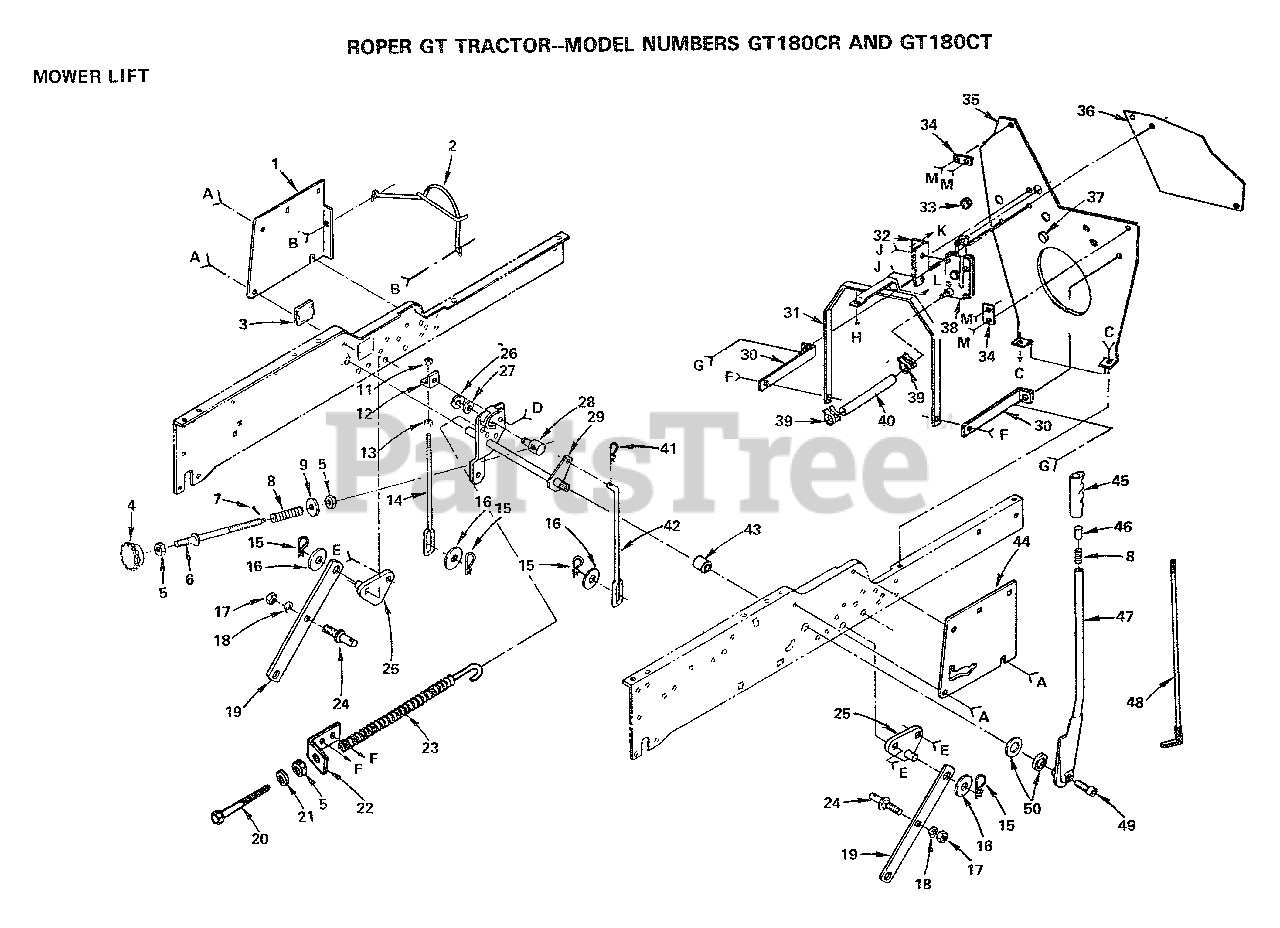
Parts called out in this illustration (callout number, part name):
2	ENGINE BELT GUARD
5	NUT
8	SPRING T
9	WASHER
11	NUT
12	BRACKET T
13	NUT.HEX.3/8-16UNC
14	LINK-LIFT MOW T
15	SPRING H
17	NUT
18	LOCKWASHER
19	SUSPENSION ARM GT
20	BOLT-ADJ SPRING T
21	WASHER
24	PIVOT STUD GT
25	SUSP BRACKET T
26	KLIP RING
27	WASHER
28	TRUNION T
29	LIFT SHAFT GT
30	BRKT-SHIELD, HEAT, SIDE
33	SNAP BUSHING T
36	PANEL-SHIELD, HEAT
37	PLUG GT
42	LIFT LINK RH T
45	GRIP
49	SCREW LT
